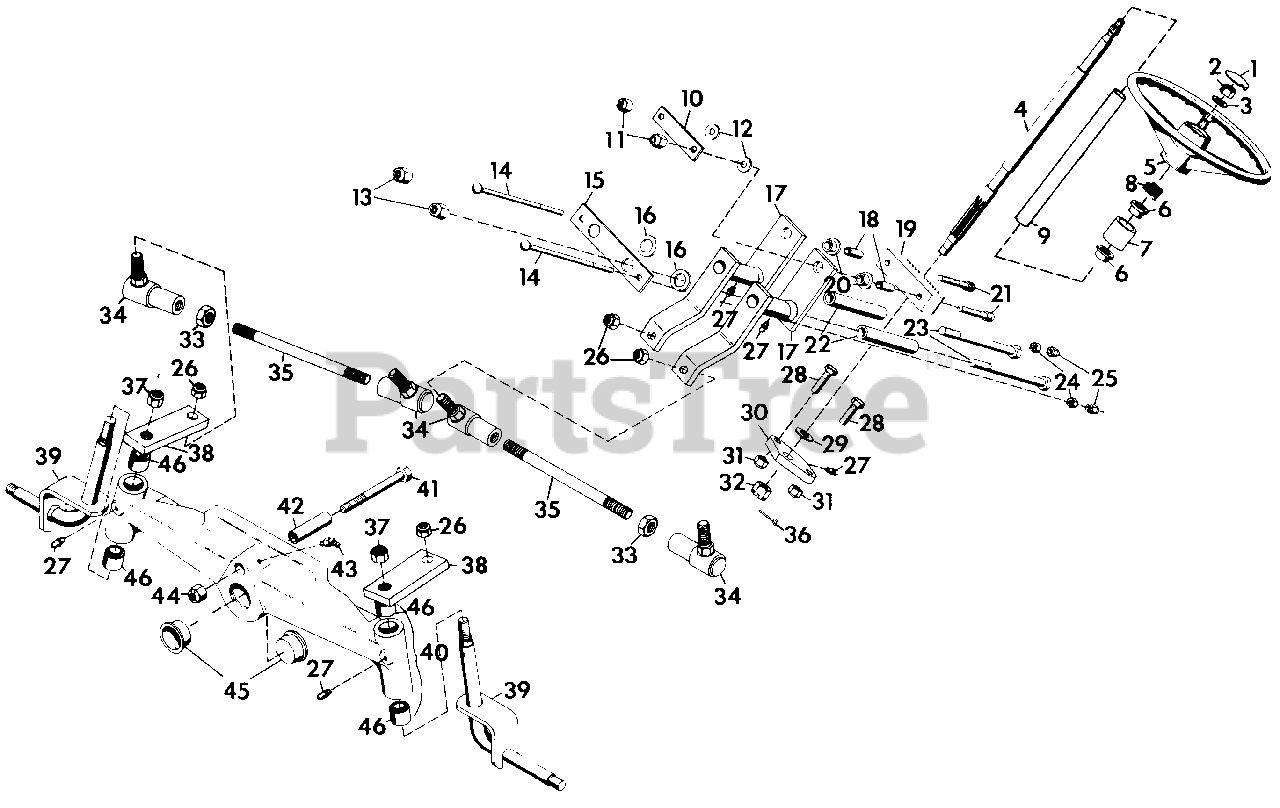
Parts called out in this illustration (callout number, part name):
1	CAP, STEERING WHEEL
2	NUT, JAM 5/8-11 HEX
3	WASHER, FLAT .656X1.312X.095
4	SHAFT, STEERING WHEEL
5	WHEEL, STEERING 8122
5	WHEEL, STEERING 8123 AND 8163-B
6	BUSHING, NYLON .760X1.000X.600 FLANGE
7	BUSHING, STEERING WHEEL
8	SPRING, COMPRESSION 1X.80X36 LB/IN
9	TUBE, PLASTIC 1.0 I.D.
10	STRAP, RACK AND PINION
11	NUT, LOCK 3/8-16
12	WASHER, FLAT .375X1.125X.065
13	NUT, LOCK 1/2-13
14	BOLT, 5/16-18X5.5 RD HD SQ NK
15	PLATE, ADJUSTMENT
16	RACE, BEARING THRUST .752X1.240X.095
17	WELDMENT, STEERING
18	BUSHING, .391X.622X.670
19	GEAR, RACK
20	BEARING, FLANGE(P/M BRONZE)
21	SCREW, CAP 3/8-16X2.0 HEX SOCKET HD
22	SLEEVE, PIVOT
23	BOLT, HEX 1/2-13X6.0
24	NUT, HEX 5/16-18
25	NUT, LOCK 5/16-18
26	NUT, LOCK 3/8-24
27	FITTING, LUBE 1/4-28
28	BOLT, HEX 7/16-14X1.5
29	RACE, THRUST
30	SUPPORT, STEERING SHAFT
31	NUT, LOCK 7/16-14
32	NUT, HEX 1/2-13 SLOTTED
33	NUT, HEX 3/8-24
34	BALL JOINT, STEERING
35	ROD, STEERING
36	PIN, COTTER .09X1.00
37	NUT, HEX 5/8-11
38	ARM, TIE ROD AXLE
39	WELDMENT, KING PIN
40	AXLE
41	BOLT, HEX 3/4-10X4.5
42	TUBE, AXLE PIVOT
43	FITTING, LUBE 45 DEG.
44	NUT, LOCK 3/4-10
45	CAP, FRONT AXLE
46	BUSHING, .877X1.004X1.0
